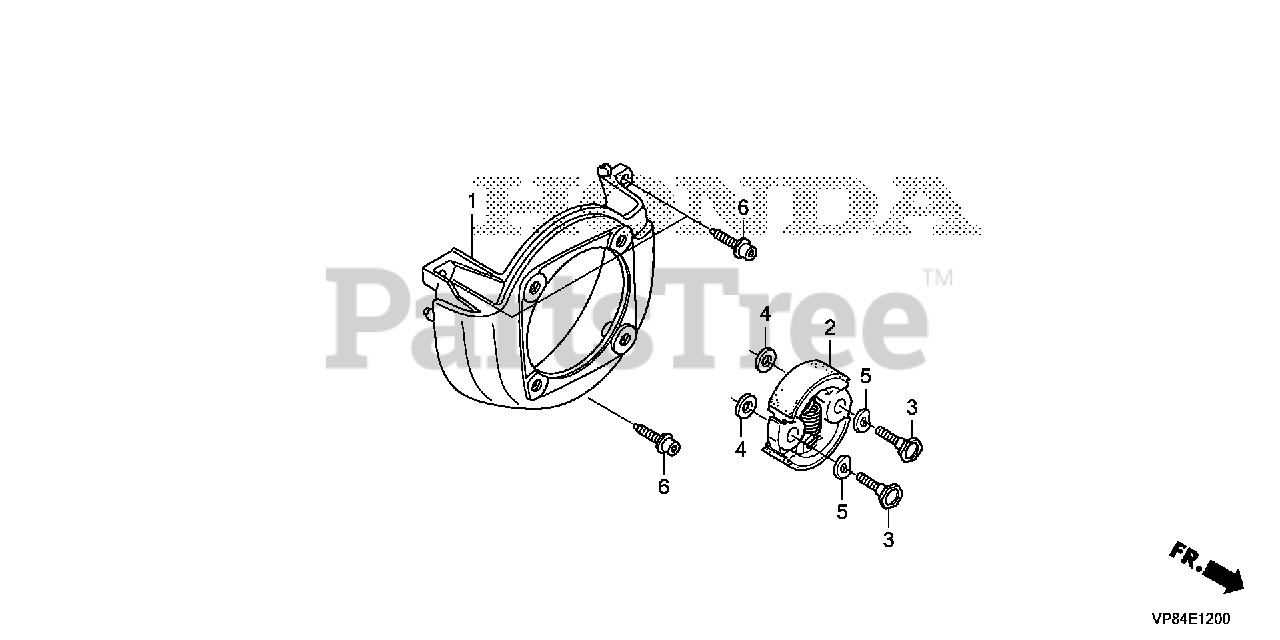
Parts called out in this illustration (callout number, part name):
1	COVER, FAN
2	CLUTCH ASSY.
3	BOLT, CLUTCH (6MM)
4	WASHER, CLUTCH (6X15)
5	WASHER, WAVE (8MM)
6	BOLT, SOCKET (5X20)
